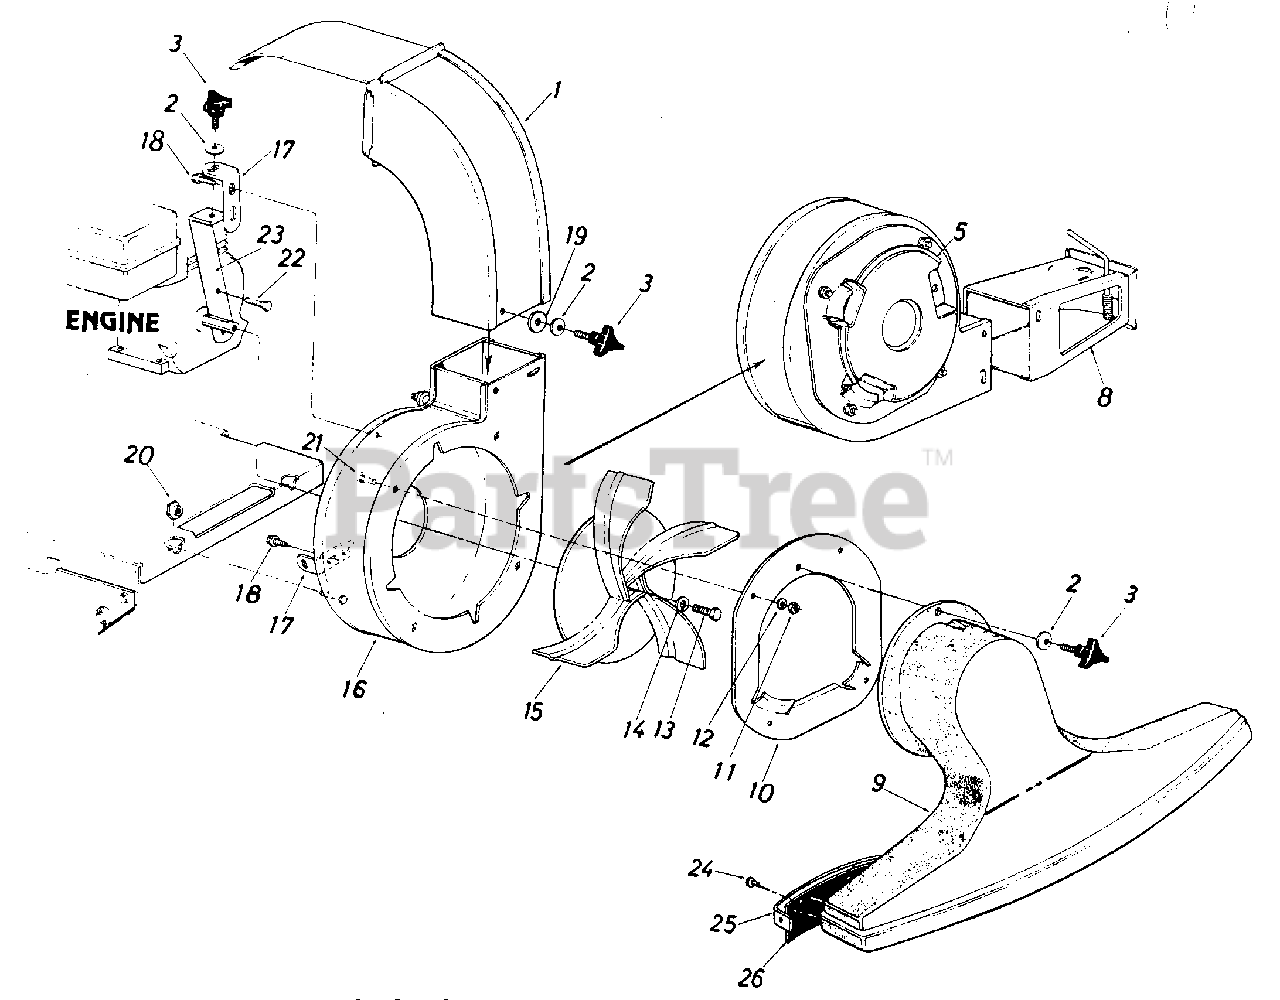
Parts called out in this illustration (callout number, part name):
3	KNOB-THREE ARM
10	PLATE ASSY-NOZZLE
11	NUT-HEX 5/16-18
12	WASHER-LOCK-5/16
13	SCREW 3/8-24X1.25 GR5
14	WASHER-HDL 3/8
15	PLATE ASSY-VANE
16	HOUSING ASSY-BLOWER
19	WASHER-FL-.312 X 1.125 X .125
20	NUT-HEX SHLD
21	BOLT-CARRIAGE 5/16-18 X .62
22	SCREW-CAP LOCK 5/16-24 X .75
